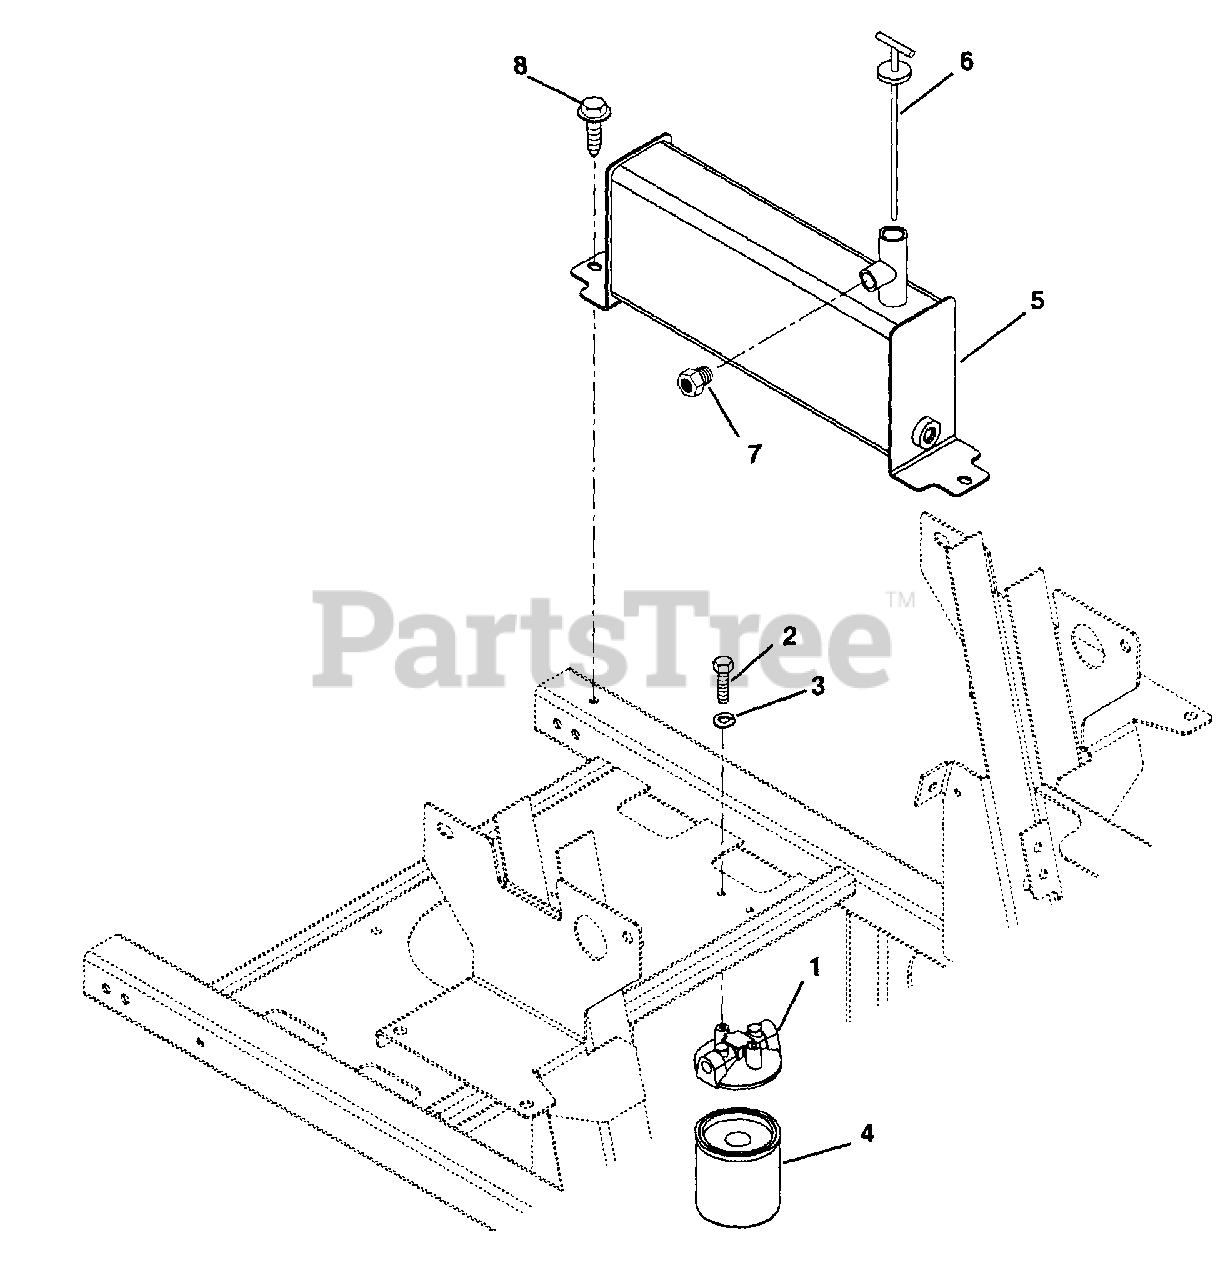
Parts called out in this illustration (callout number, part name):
1	HEAD, FILTER
2	@BLT-HEX .25-20X.50 GR5 YWZC
3	@WSHR-LK .25X.062 REG YWZC
4	ELEMENT, FILTER BE-40-0
5	TANK, HYDRAULIC WMT - ORANGE
6	DIPSTICK, HYDRAULIC TANK
7	PLUG, BREATHER 3/8"
8	@SCR-TAP .38-16X.75 HWH TR YWZ
